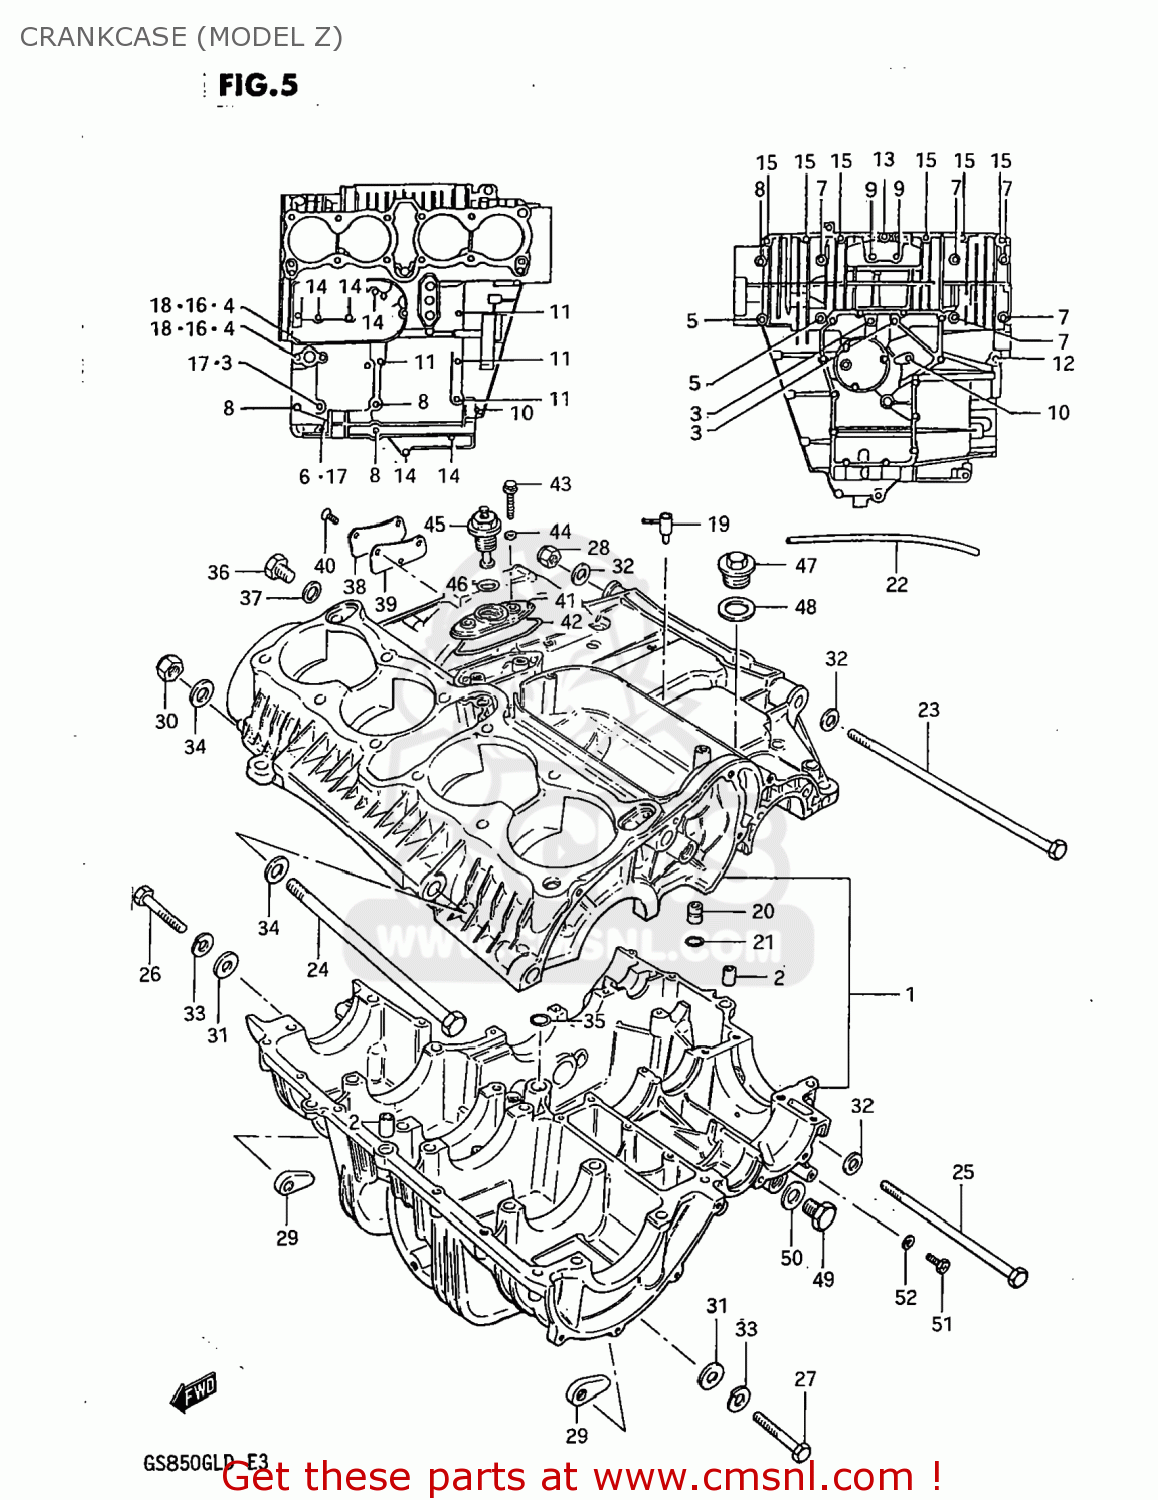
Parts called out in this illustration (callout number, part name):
1	CRANKCASE SET
2	PIN
3	BOLT
4	BOLT
5	BOLT
6	BOLT
7	BOLT 8X90
8	BOLT 8X65
9	BOLT
10	BOLT (6X90)
11	BOLT (6X75)
12	BOLT
13	BOLT ,6X50
14	BOLT,UNDER
15	BOLT 6X35
16	NUT
17	NUT
18	GASKET 8.2X14X1 (NAS)
19	BPLUG,BEVEL GEAR BREATHER
20	UNION
21	O RING(D:1.05,ID:3.1)
22	HOSE
23	BOLT 10X270
24	SHAFT,REAR SWING ARM
25	BOLT(10X165)
26	BOLT 10X60
27	BOLT (10X50)
28	NUT
29	NUT
30	NUT 12MM
31	WASHER(10.5X20X3.2)
32	WASHER
33	LOCK WASHER
34	WASHER
35	O RING(D:3.2,ID:12.9)
36	PLUG (14X12)
37	GASKET(14X19.2X2) (NAS)
38	CAP,OIL GALLERY
39	GASKET,OIL GALLERY (MCA)
40	SCREW
41	HOUSING,OIL PRESSURE SWITCH
42	O RING,PRESSURE SWITCH HOUSING
43	BOLT
44	GASKET (NAS)
45	SWITCH ASSEMBLY
46	O RING(D:1.9,ID:18.8)
47	PLUG
48	GASKET
49	PLUG
50	GASKET(14X19.2X2) (NAS)
51	SCREW(6X10)
52	GASKET (NAS)
